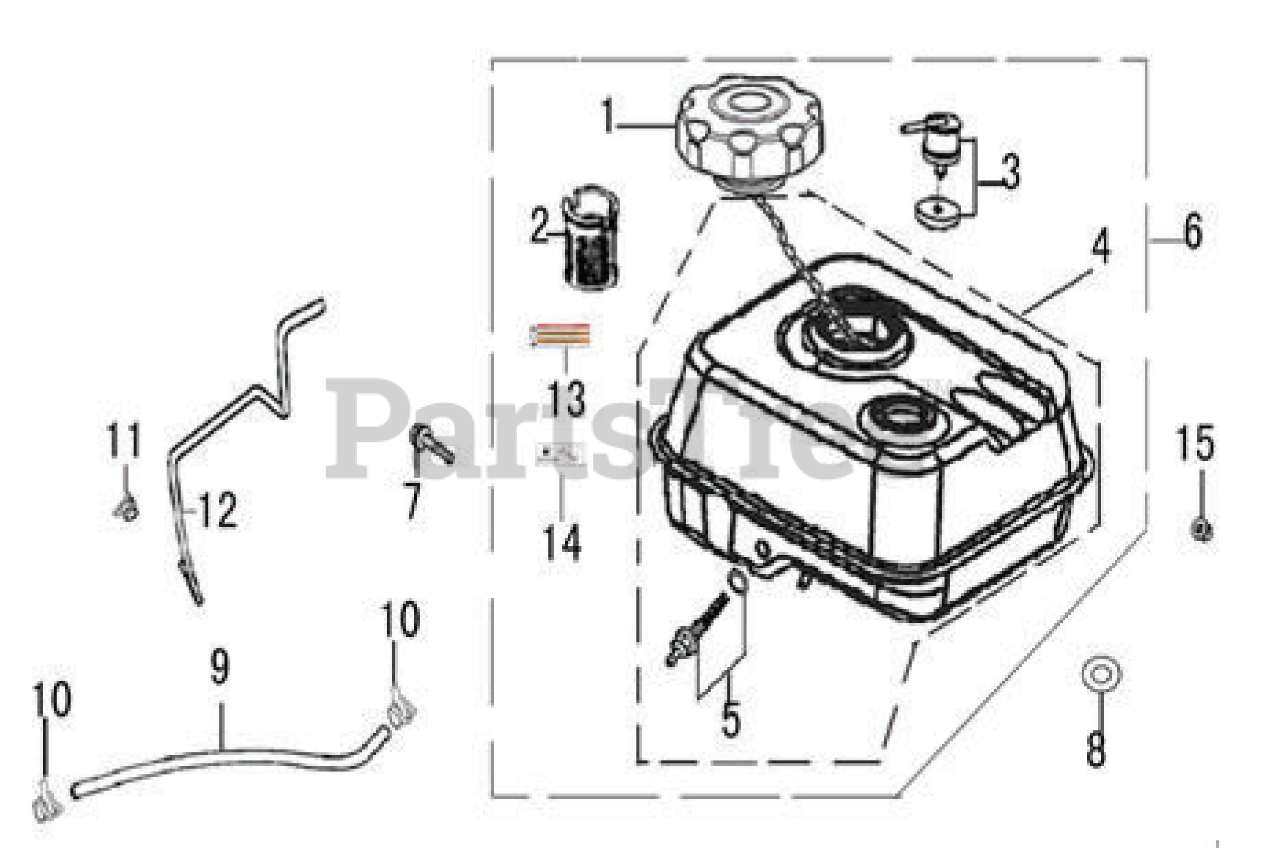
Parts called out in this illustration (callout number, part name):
1	CAP COMPLETE, FUEL FILLER
2	FILTER, FUEL
3	GAS VALVE, FUEL TANK
4	TANK COMPLETE, FUEL
5	JOINT ASSEMBLY, FUEL TANK
6	TANK ASSEMBLY, FUEL WITH ROLL OVER VALVE
7	BOLT, FLANGE, 6X25
8	WASHER, RUBBER
9	TUBE, FUEL
10	CLAMP, FUEL HOSE
11	CLAMP, HOSE
12	HOSE, PREFORMED
13	WARNING MARK
14	REMINDER MARK
15	NUT, FLANGE
